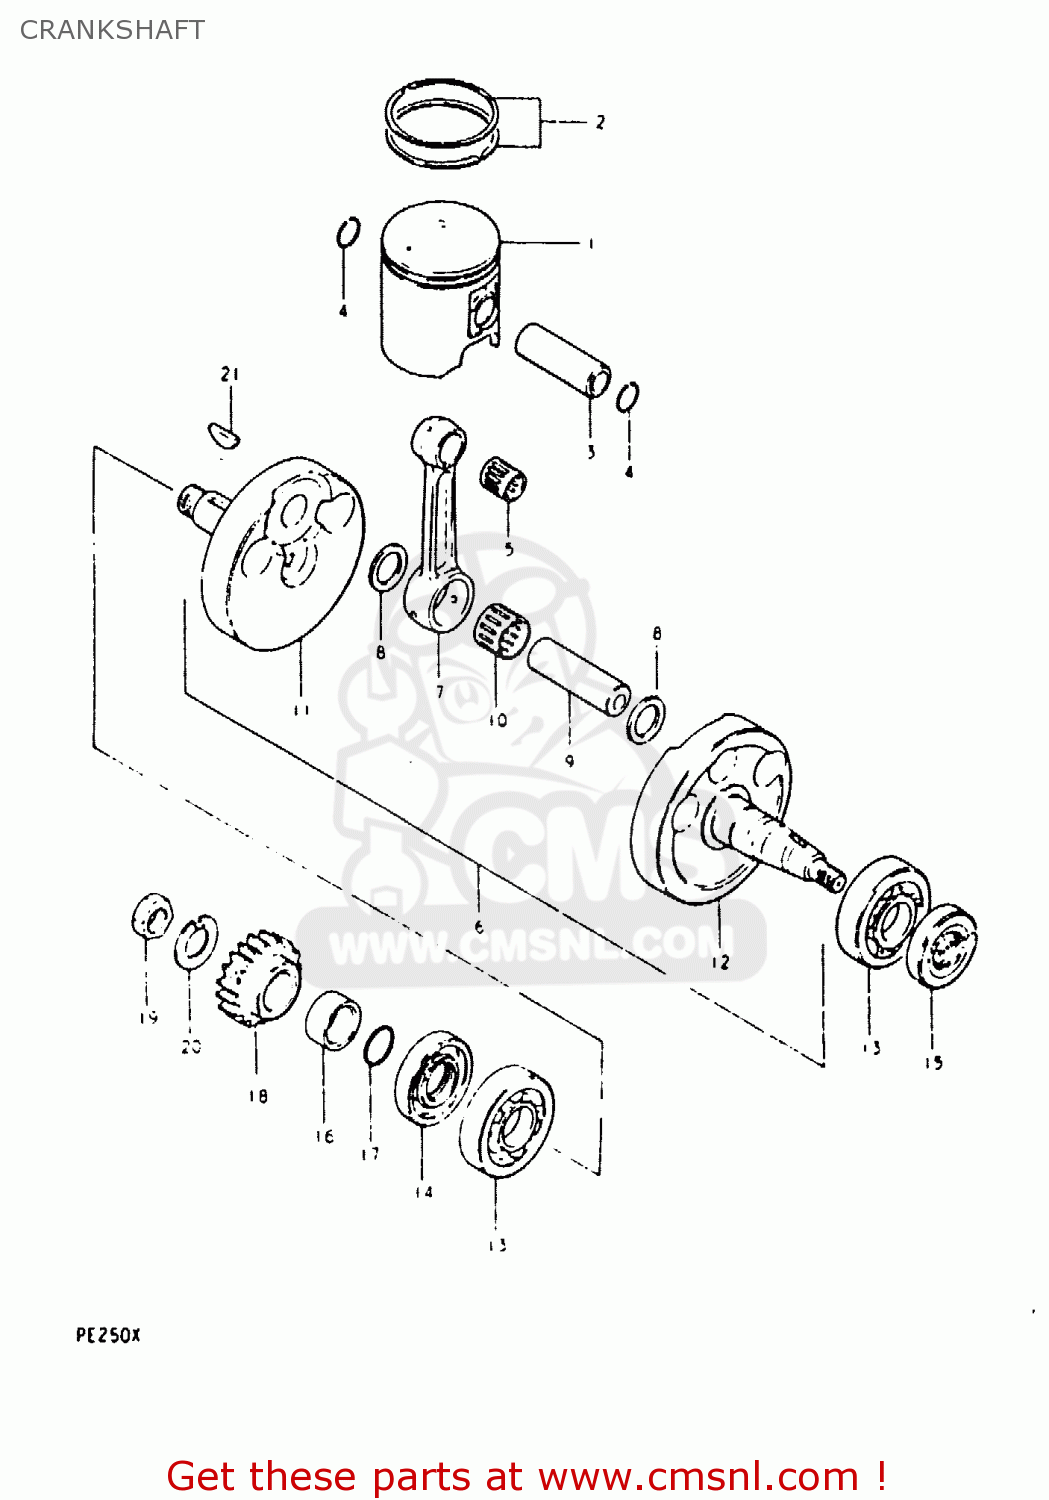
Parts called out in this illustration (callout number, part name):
1	PISTON
2	RING SET,PISTON
3	PIN,PISTON (18MM)
4	CIRCLIP,PISTON PIN
5	BEARING(18X23X22)
6	CRANKSHAFT ASSEMBLY
7	ROD,CONNECTING
8	WASHER(24X29X1.5)
9	PIN,CRANK
10	ROLLER BEARING (24X30X1
11	CRANKSHAFT
12	CRANKSHAFT,LEFT
13	BEARING
14	SEAL,OIL(32X52X8.4)
15	SEAL,OIL(24X50X9)
16	SPACER
17	O RING(D:2.4,ID:19.8)
18	GEAR,PRIMARY DRIVE
19	NUT
20	WASHER
21	KEY
